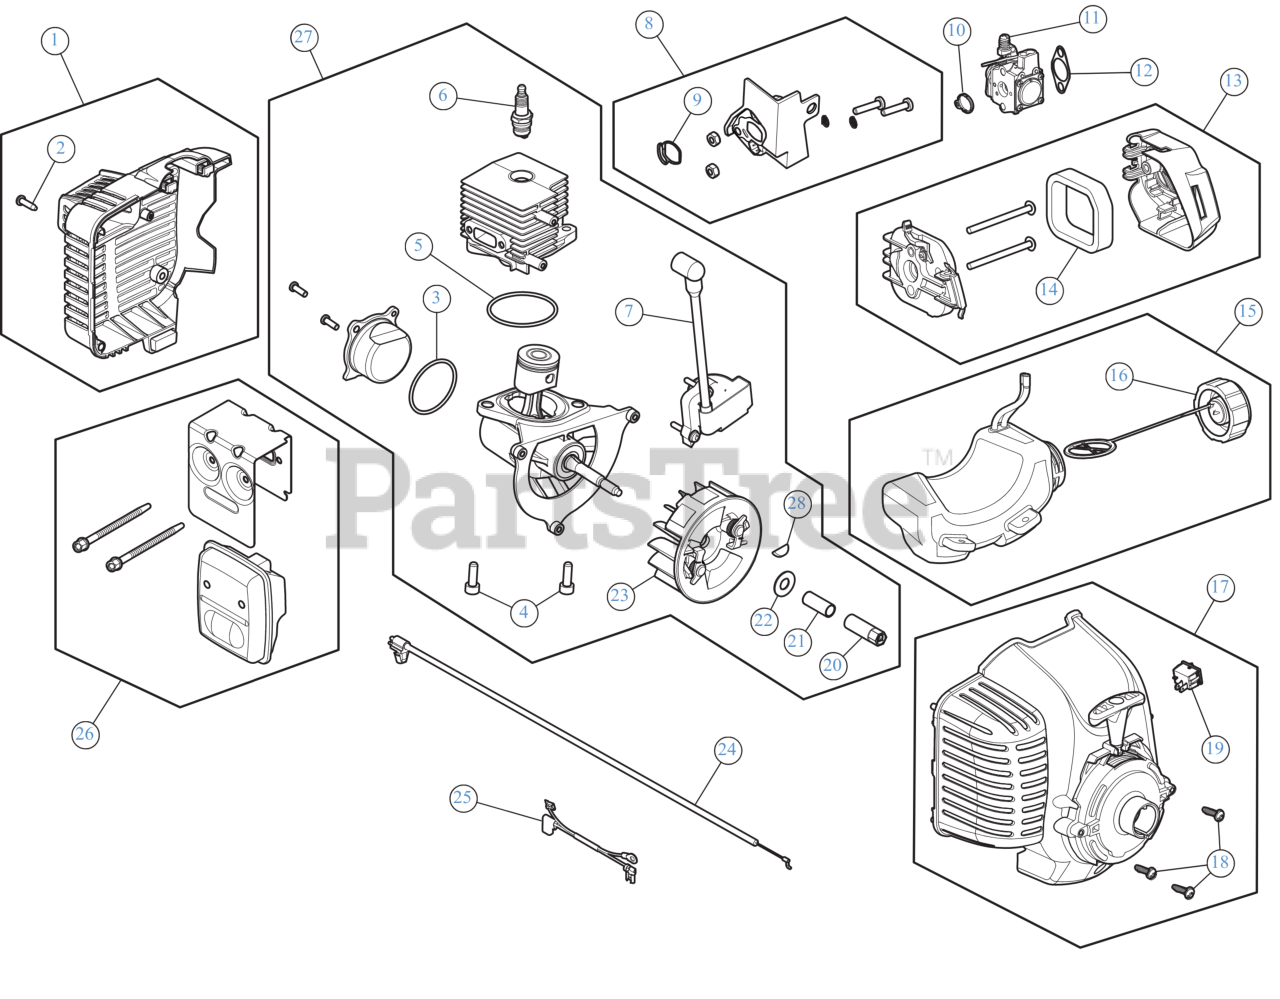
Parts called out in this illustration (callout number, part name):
1	HOUSING ASSEMBLY RR
2	SCREW 8-16 x 3/4
3	O-RING SEAL CRANKCASE
4	SCREW 5/16-18x3/4 T40
5	O-RING SEAL CYLINDER
6	SPARK PLUG
7	MODULE ASSEMBLY
8	INTAKE ASSEMBLY
9	INSL/CYL SEAL
10	CARBURETOR SEAL
11	CARBURETOR
12	GASKET CARB
13	AIR CLEANER
14	AIR FLITER
15	FUEL TANK ASSEMBLY
16	FUEL CAP ASSEMBLY
17	STARTER HOUSING
19	SW, MOMENTARY ON/O
20	POWER SHAFT ADAPTER
21	SPACER CRANKSHAFT
22	BELL WASHER
23	FLYWHEEL ASSEMBLY
24	THROTTLE CABLE
25	SHORT WIRE LEAD
26	MUFFLER ASSEMBLY
27	SHORT BLOCK
28	WOODRUFF KEY #403-.125 x .375
